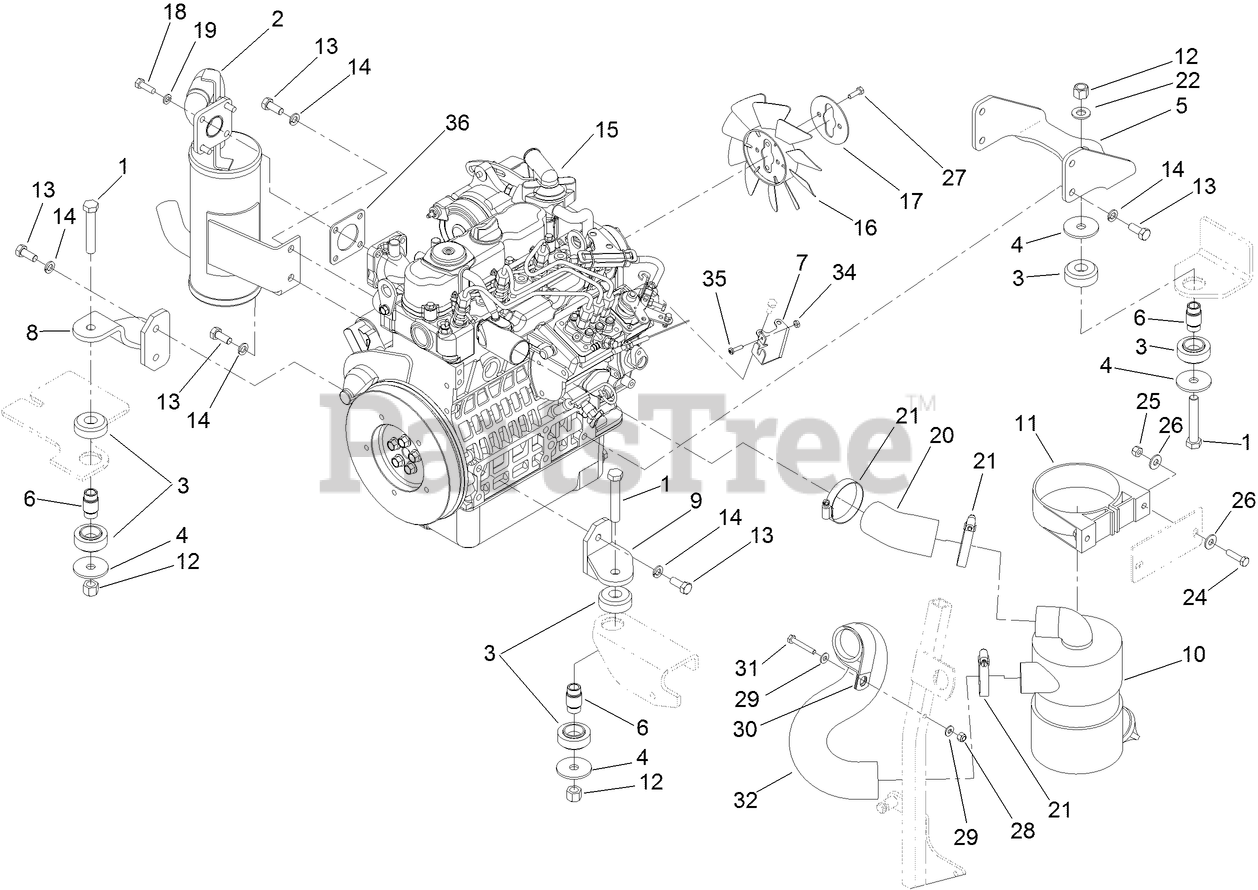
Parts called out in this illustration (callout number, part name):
1	SCREW-HH
2	MUFFLER
3	MOUNT-ISOLATION ASM
4	WASHER-LARGE
5	BRACKET-ENGINE MOUNT, REAR
6	SPACER
7	BRACKET-SUPPORT, THROTTLE
8	SUPPORT-ENGINE, RH
9	SUPPORT-ENGINE, LH
10	AIR CLEANER ASM
11	BRACKET-MOUNTING
12	NUT-LOCK, NI
13	SCREW-HH
15	ENGINE-KUBOTA, D902-E4B-TOR-1
17	PLATE-REATAINER, FAN
18	SCREW-HH
19	SCREW-HH
20	HOSE-INTAKE, AIR CLEANER
21	CLAMP-HOSE
22	WASHER-FLAT
24	SCREW-HH
25	NUT-LOCK, NI
26	WASHER-PLAIN
27	SCREW-HH
28	NUT-LOCK, NI
29	WASHER-FLAT
30	CLIP-LOOM
31	SCREW-HH
32	HOSE-INTAKE, ENGINE
34	NUT-HEX
35	SCREW-TORX
36	GASKET-MUFFLER
